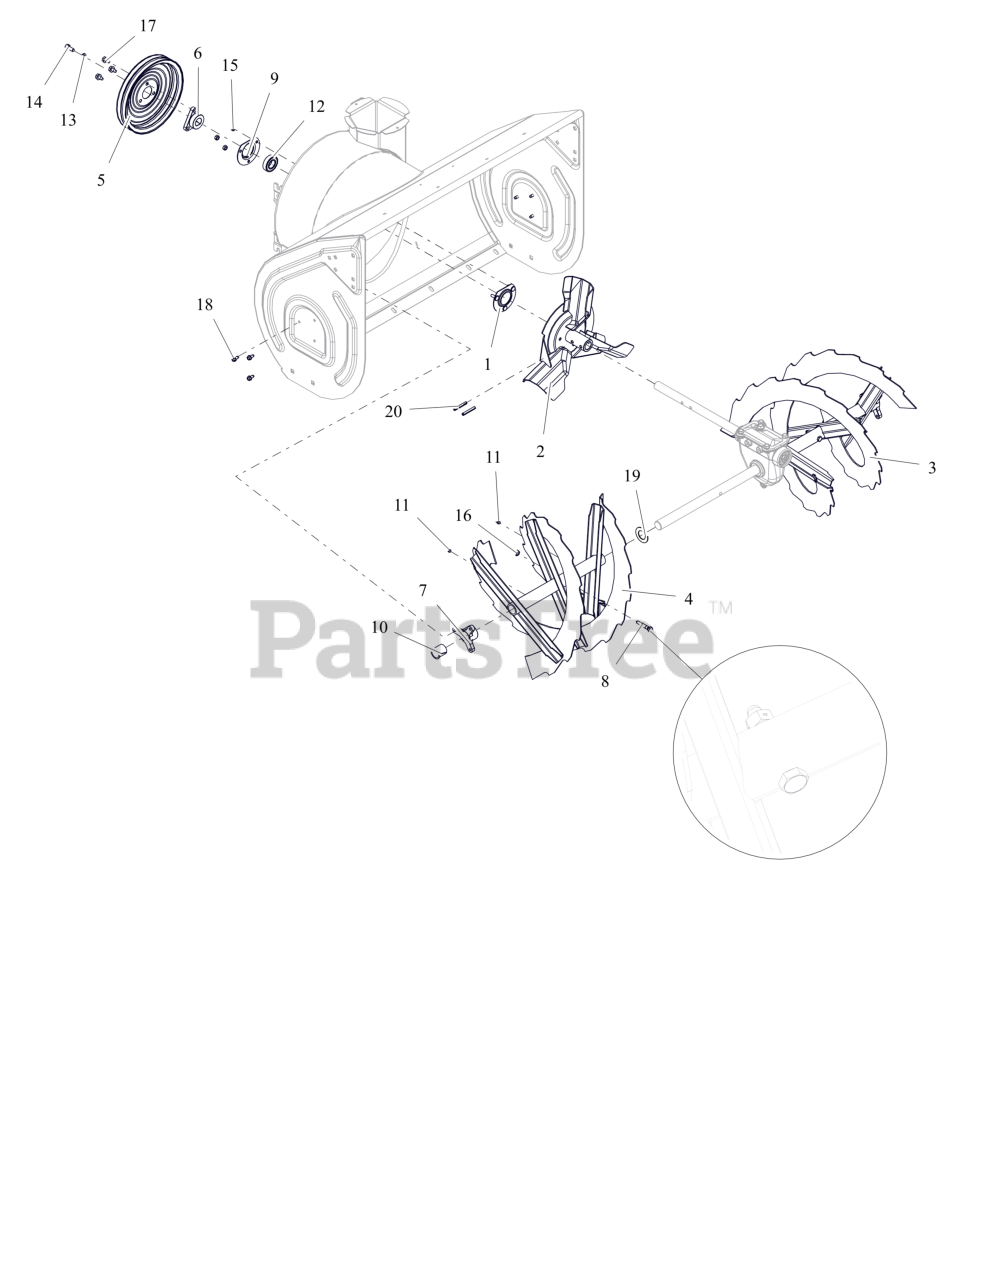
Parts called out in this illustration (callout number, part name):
1	BEARING FLANGE
2	IMPELLER, 3 BLADE-14"
3	RAKE, LH-32"(1 ID X 15.75 OD)
4	RAKE, RH-32"(1 ID X 15.75 OD)
5	PULLEY, SPIN FORM DUAL GROOVE
6	PULLEY HUB, D-BORE .87 PRO
7	BUSHING, RAKE SHAFT 1"
8	SHEAR BOLT SERVICE ASSEMBLY
9	BEARING FLANGE
10	BSHG-FLG SPLIT NYLINER 1.0" HP
11	ZERK,FITTING .25X.125 DRIVE IN
12	BRG-BALL .876X1.75X.50 RSTFP
13	WSHR, LK-HVY .312X.097 ZCC
14	BLT, HEX .31-24X.750 G5 ZCC
15	NUT,LK-CTR .25-20 GA ZCC
16	NUT,LK-CTR .31-18 GA ZCC
17	SCR,TAP .312-18X.50 HWH TR ZCC
18	SCR-TAP .25-20X.50 HWH ZCC
19	WSHR- FLT 1.010X1.755X.062 ZCC
20	PIN-ROLL .250X1.75
